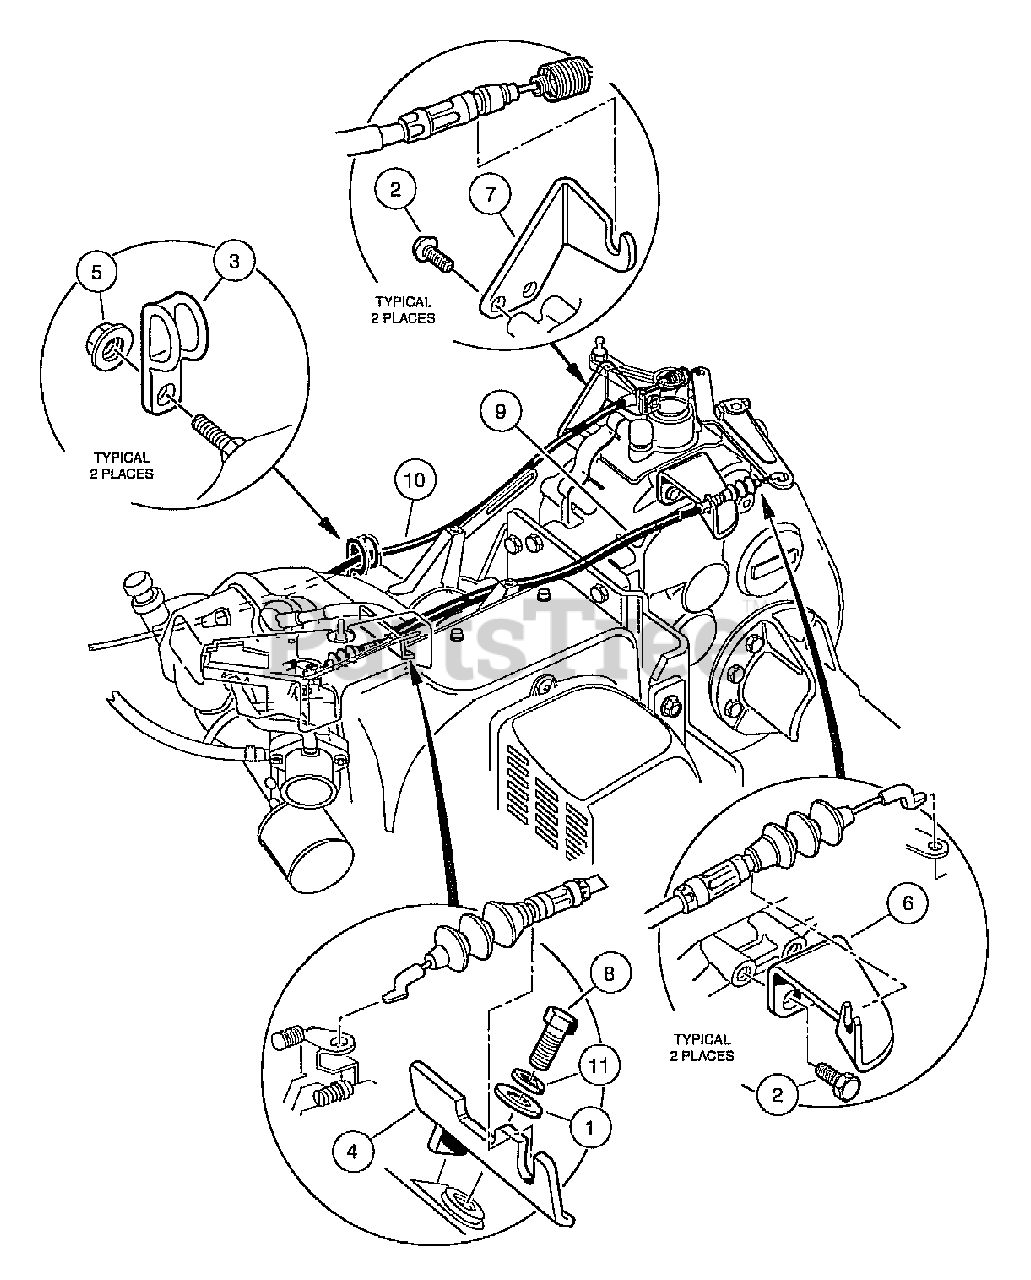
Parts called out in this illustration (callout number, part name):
1	Washer, 5/16 Flat
2	Screw, 1/4 X 0.625 Hex-Head
4	Bracket, Cable Snap-In
6	Bracket, Rear, Cable Snap-In
7	Bracket, Rear, Cable Snap-1n
8	Screw, MB-1.25 X 24mm Hex Head
9	Cable, Governor, Snap-In
10	Cable, Accelerator, Snap-In
11	Lockwasher, 5/16 Split
